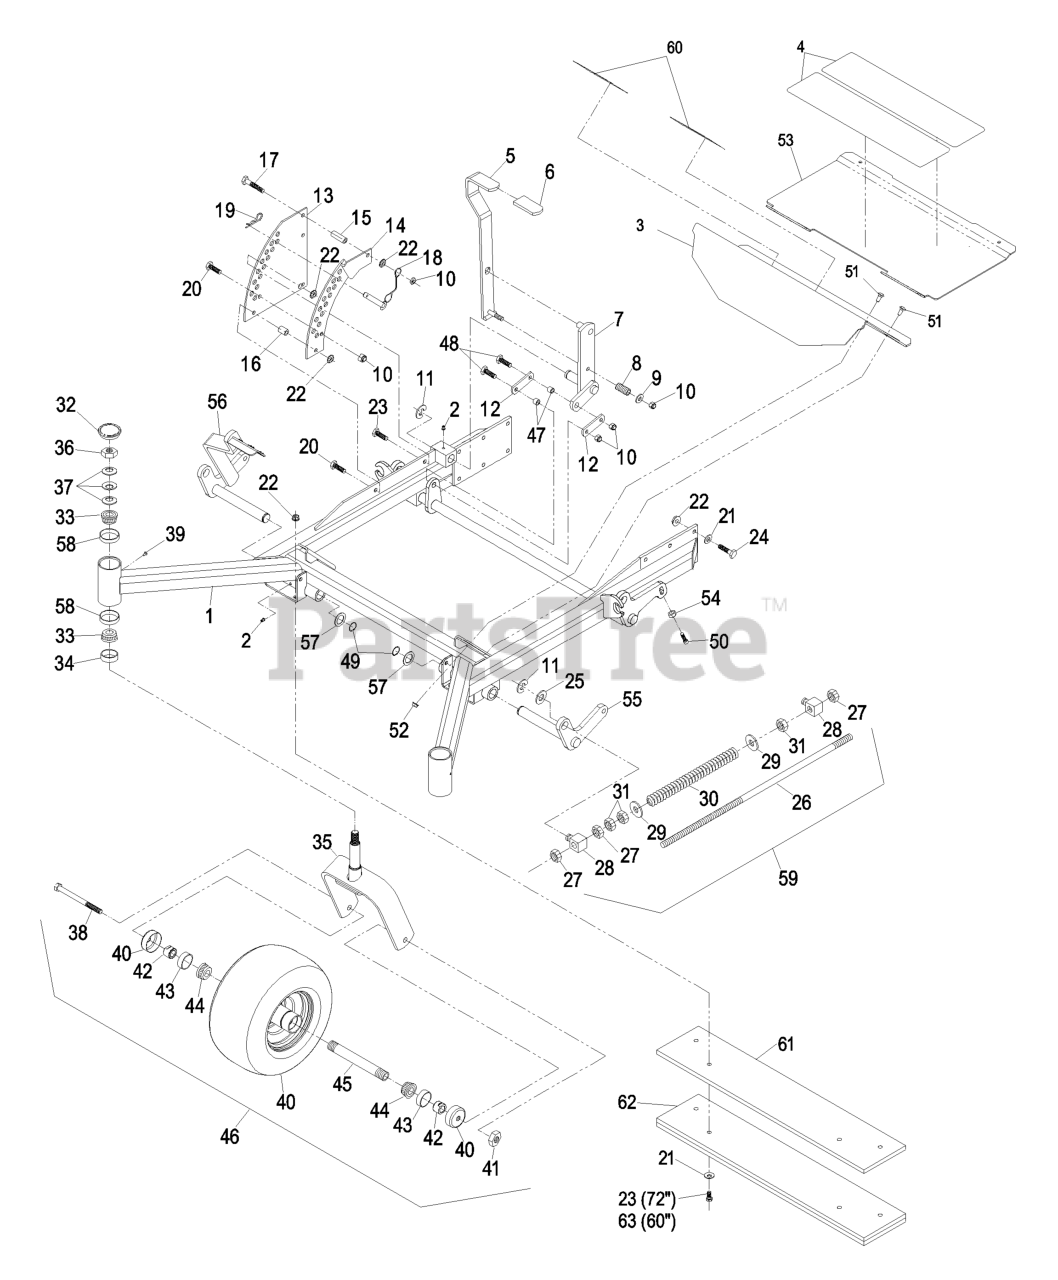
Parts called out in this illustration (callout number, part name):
1	KIT,FRONT FRAME XP 60
2	FITTING-GREASE
4	PAD-ANTISKID
5	LIFT LEVER/GRIP ASM
6	GRIP-LEVER, LIFT
7	ARM-LIFT, DECK
8	SPRING-COMPRESSION
9	WASHER-FLAT
10	NUT-LOCK, NI
11	RING-RETAINING, EXT
12	ARM-LIFT, DECK
13	PLATE-LIFT, DECK
14	PLATE-LIFT, DECK
15	BUSHING-LEVER, LIFT
16	BUSHING-LEVER, LIFT
17	SCREW-HH
18	PIN-HITCH (W/LANYARD)
19	PIN-COTTER
20	SCREW-HH
21	WASHER-BELLEVILLE
22	NUT-HHF, WHIZ
23	SCREW-HH
24	SCREW-HH
25	WASHER-FLAT
26	ROD-LIFT, DECK
27	NUT-HEX
28	SWIVEL-DECK MOUNT, REAR
29	WASHER-FLAT
30	SPRING-SUPPORT, DECK
31	NUT-JAM
32	CAP-GREASE
33	Cone-Bearing Tapered Roller
34	SEAL-GREASE
36	NUT-LOCK, NI
37	WASHER-BELLVILLE
38	SCREW-HH
40	GUARD-SEAL
41	NUT-LOCK, NI
42	SPACER-NUT
43	SEAL-CASTER
44	BEARING-CONE, TAPERED ROLLER
47	BUSHING
48	SCREW-HH
49	RING-RETAINING
50	SCREW-HSH
51	BOLT-CARR
53	ASM,LIFTOUT FLOORPAN/PAD
54	NUT-JAM
55	WLD, FRONT LIFT SHAFT - L
56	WLD, FRONT LIFT W/ LEVER
57	WASHER-SPACER
58	CUP-BEARING
59	FRONT FRAME SPRING ASM
60	PAD-ANTI SKID
62	WEIGHT BAR ASM
63	SCREW-HH
